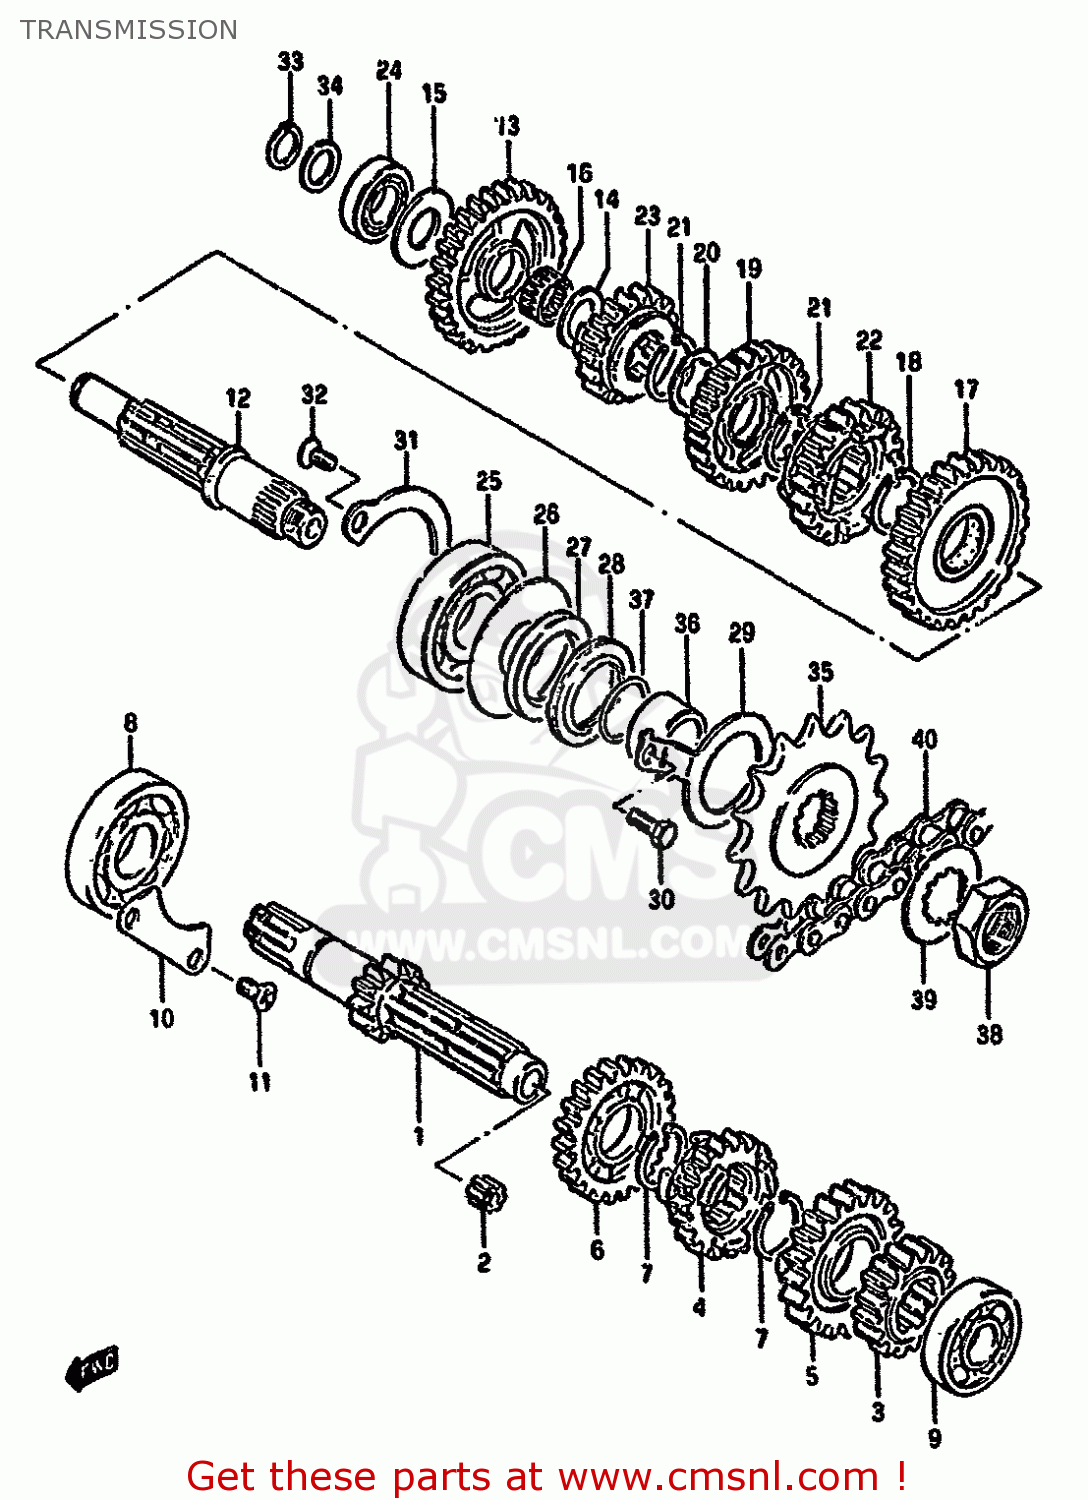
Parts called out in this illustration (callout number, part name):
1	SHAFT,COUNTER
2	BUSH
3	GEAR,2ND DRIVE(NT:16)
4	GEAR,3RD DRIVE(NT:19)
5	GEAR,FOURTH DRIVE
6	GEAR,FIFTH DRIVE
7	CIRCLIP
8	BEARING
9	BEARING(17X40X12)
10	RETAINER,CNTR SHAFT BEARING
11	SCREW
12	SHAFT,DRIVE
13	GEAR,1ST DRIVEN(NT:29)
14	WASHER
15	WASHER
16	BEARING(17X21X9.8)
17	GEAR,2ND DRIVEN(NT:27)
18	CIRCLIP
19	GEAR,THIRD DRIVEN
20	WASHER,LOCK
21	CIRCLIP
22	GEAR,FOURTH DRIVEN
23	GEAR,FIFTH DRIVEN
24	BEARING(17X36X12)
25	BEARING(22X56X16)
26	WASHER(35X55X1)
27	OIL SEAL (30X43X5)
28	OIL SEAL (30X43X7)
29	RETAINER,DRIVE SHAFT OIL SEAL
30	BOLT
31	RETAINER,DRIVE SHAFT BEARING
32	SCREW
33	CIRCLIP
34	WASHER
35	SPROCKET,ENGINE(NT:15)
36	SPACER
37	O RING(D:2.5,ID:21)
38	NUT
39	WASHER,LOCK
40	CHAIN(DID520VC5,100LE)
